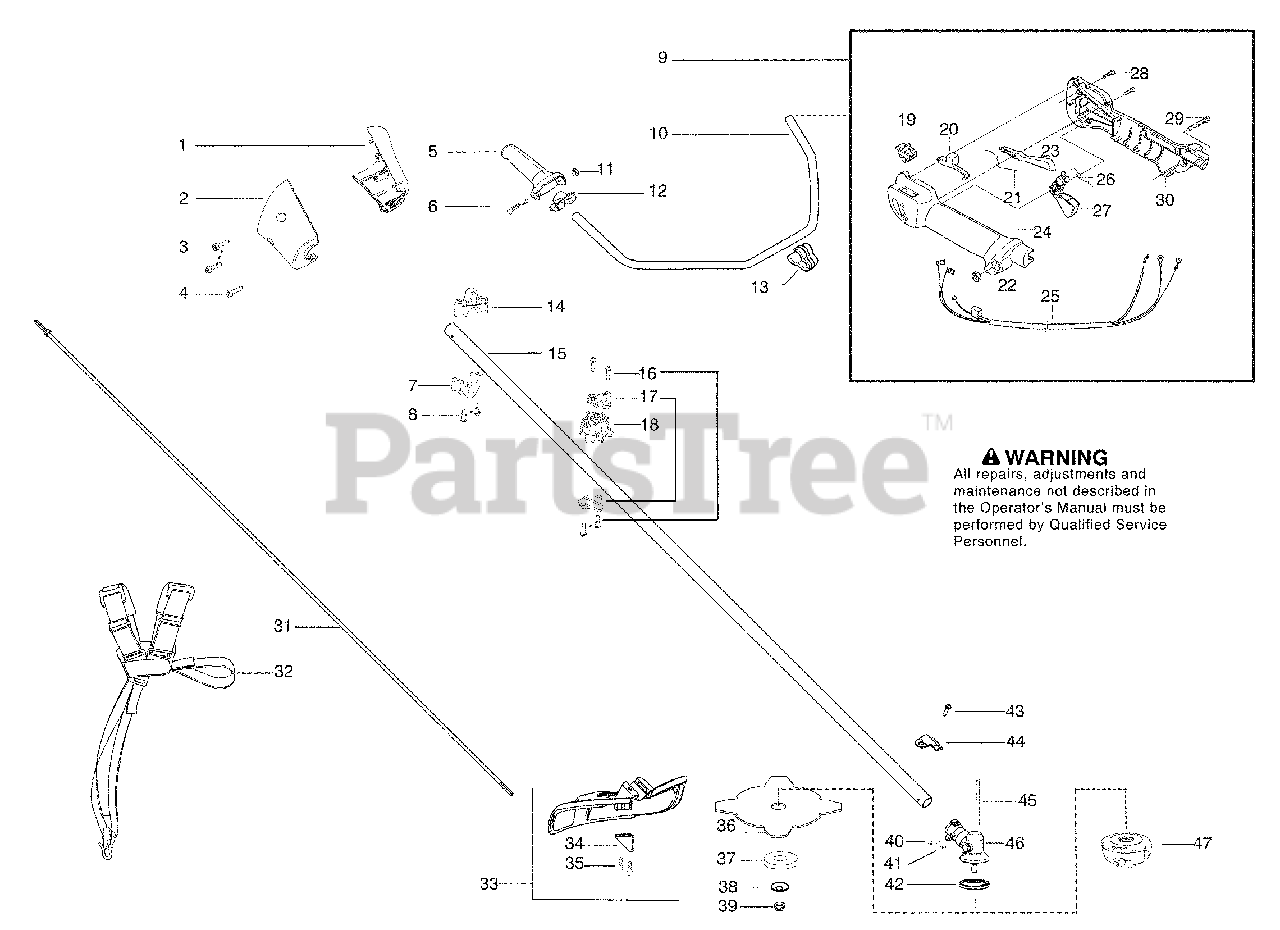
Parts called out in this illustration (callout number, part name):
1	Nose Cone - LH
2	Nose Cone - RH
5	Handle-Assist
7	Clamp-Harness
9	Assy-Throttle Housing
12	Cover-Assist Handle
13	Clip-Handlebar
14	Clamp-Harness
15	Kit-Driveshaft
16	Screw
17	Clamp - Bracket
18	Clamp 1" Handlebar
19	Switch-Stop
20	Lockout-Starter Throttle
21	Spring - Lockout
23	Lockout - Throttle
24	Housing - Throttle -LH
25	Assy - Cable Wire
26	Spring - Trigger
27	Trigger - Throttle
29	Screw
30	Housing-Throttle - RH
32	Harness w/o warning
33	Kit-Shield
34	Limiter - Line
36	Blade - Grass
37	Cup-Support
38	Support - Flange
39	Locknut - Blade
42	Driver Disc
44	Bracket - Shield
45	Pin - Locking
46	Assy - Gearbox
47	Assy-T25 Cutting Head
